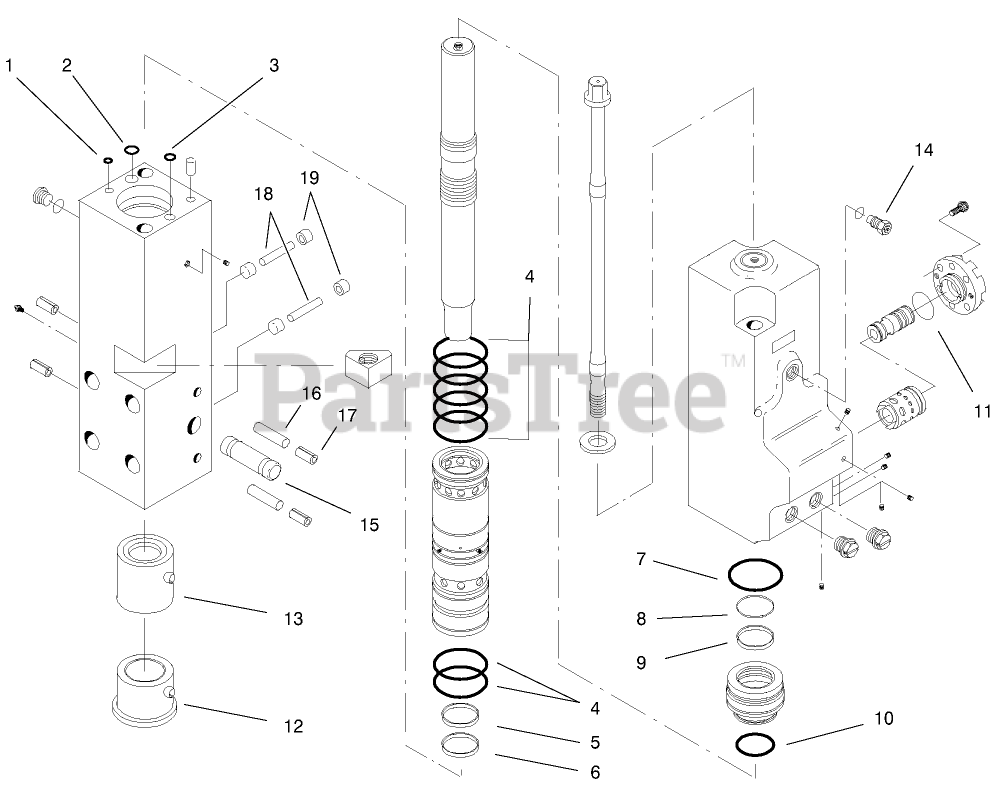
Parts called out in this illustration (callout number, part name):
6	Wiper-Rod
8	Modified Quad Ring
12	LOWER BUSHING
13	UPPER BUSHING
14	CHARGE VALVE
16	DOWEL PIN
17	SPIRAL PIN
18	PIN RETAINER
